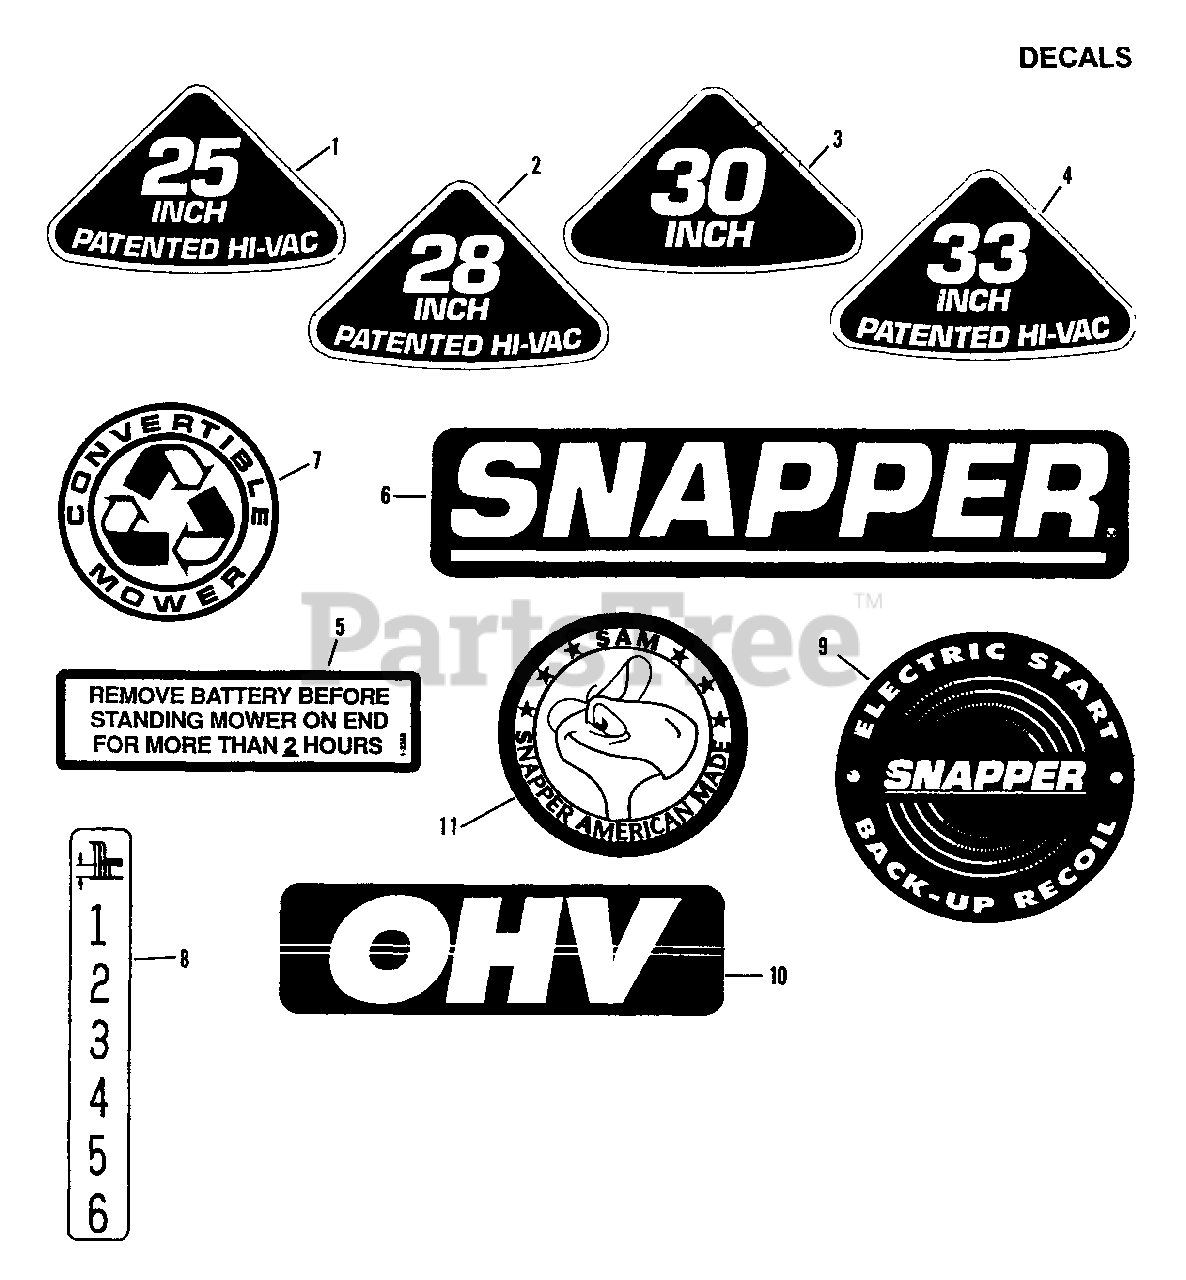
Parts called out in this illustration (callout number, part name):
1	DECAL, 25 Inch
2	DECAL, 28 Inch
3	DECAL, 30 Inch
4	DECAL, 33 Inch
5	DECAL, Battery
6	SNAPPER, (Molded Logo)
7	LOGO, Convertible (Silver)
8	DECAL, Height of Cut
9	DECAL, Back-Up Recoil
10	DECAL, OHV
11	MEDALLION, Sam
